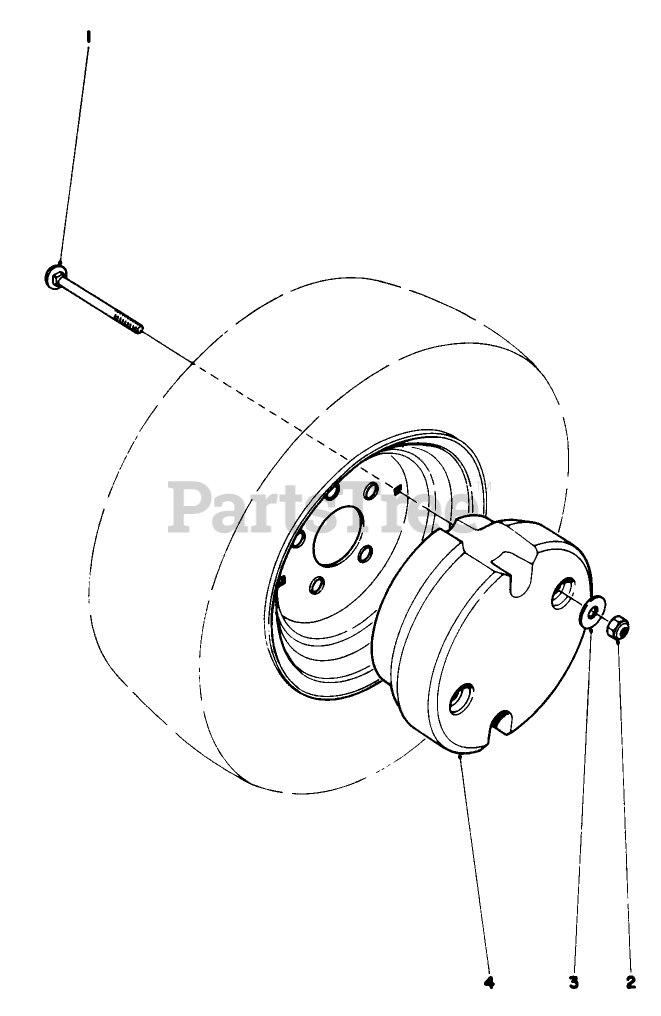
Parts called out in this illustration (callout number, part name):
1	SCREW-CARR
2	NUT-LOCK, NI
3	WASHER-FLAT
4	Weight-Wheel
